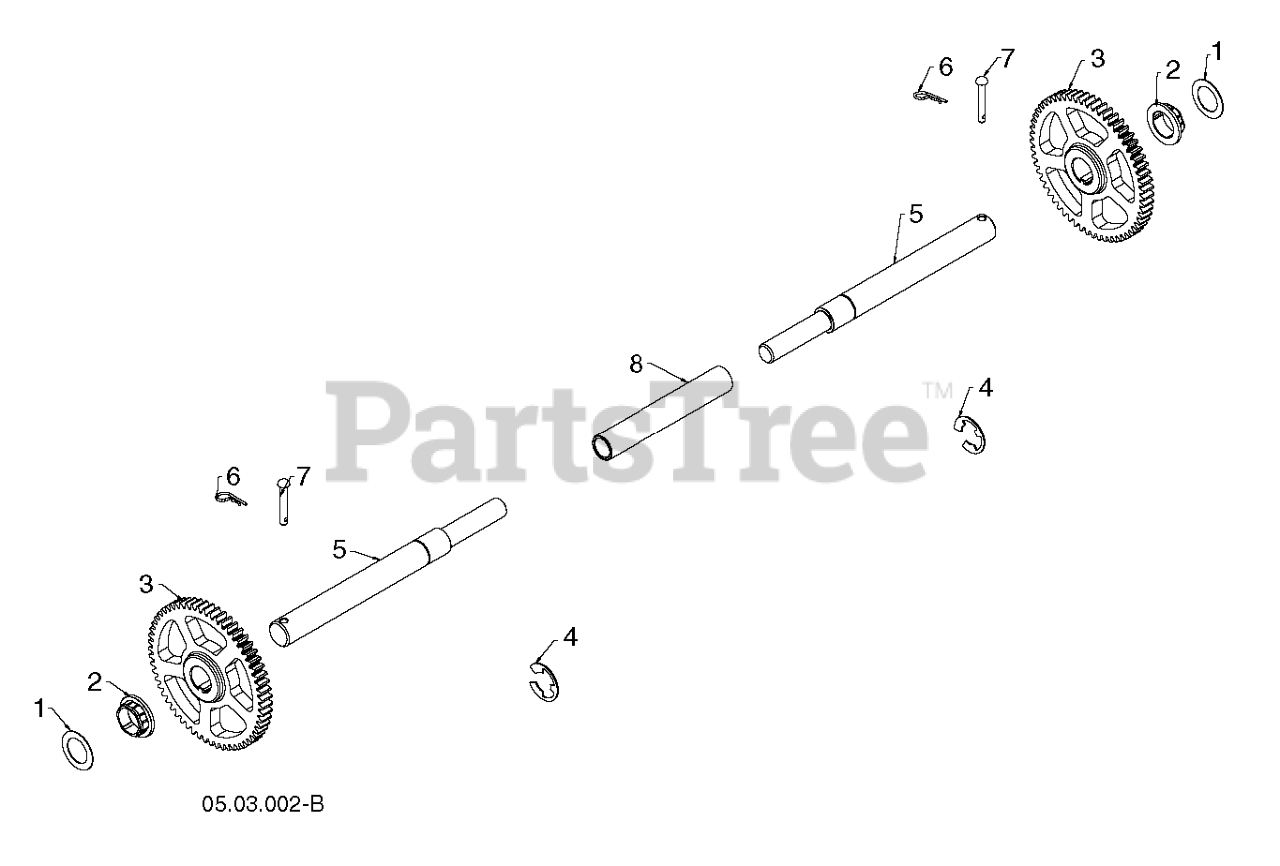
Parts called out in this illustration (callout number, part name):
1	WASHER 1.00
2	BUSHING.HEX.1.SHAFT
4	E RING HYT
5	AXLE AXLE, SPLIT SHAFT
6	RETAINER M
7	RIVET
8	SLEEVE SLEEVE, AXLE SLEEVE
